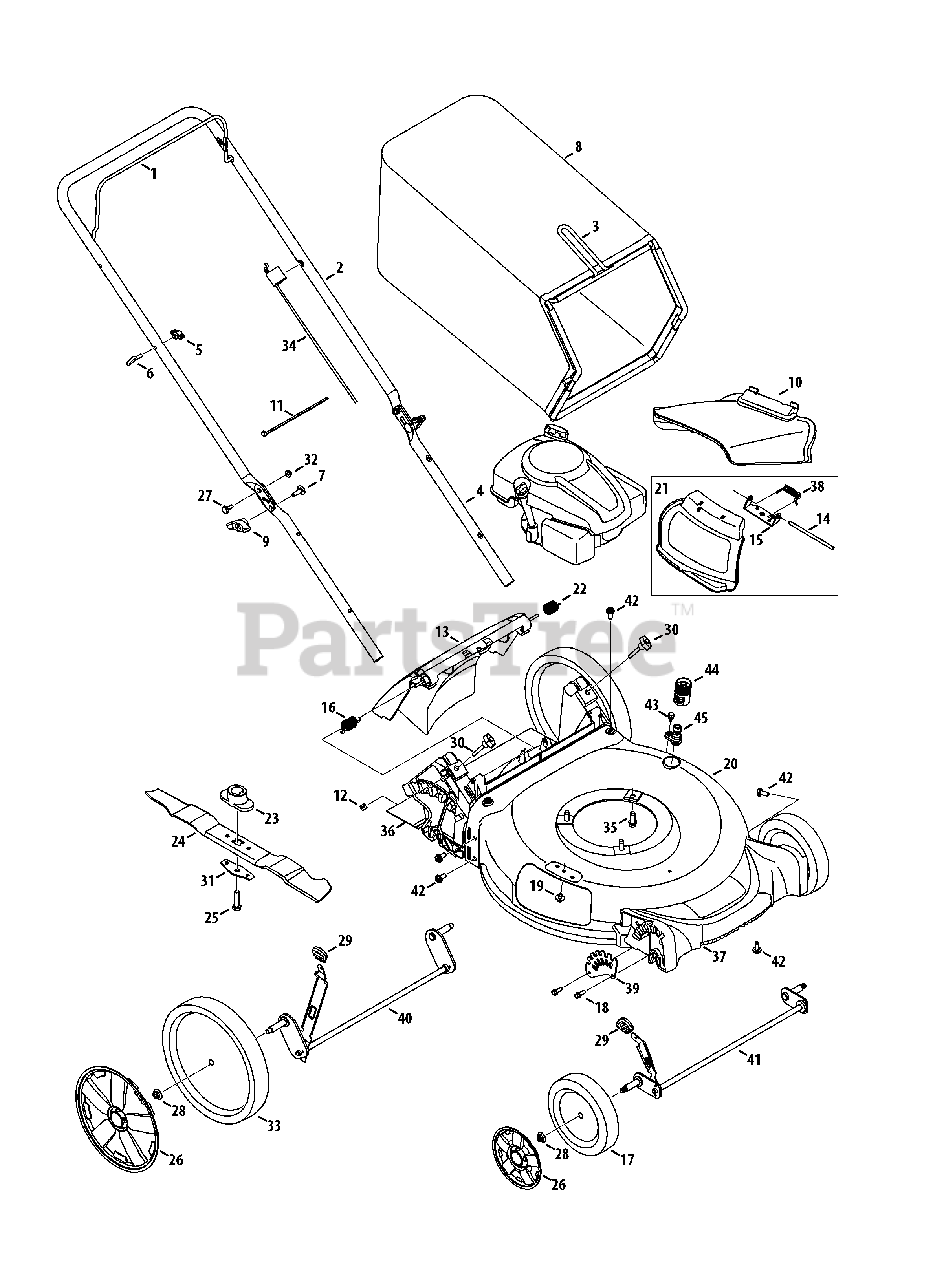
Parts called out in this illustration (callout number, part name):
1	Blade Control
2	Upper Handle
4	Lower Handle
5	Wing Nut
6	Rope Guide
7	Carriage Screw ,5/16-18
8	Grass Bag
9	Wing Knob
10	Side Chute
11	Cable Tie
12	Nut, Sq., 1/4-20
13	Rear Discharge Door Assembly
14	Hinge Pin
15	Chute Deflector Bracket
16	Torsion Spring - RH
17	Wheel, 7 x 2
18	Screw, 1/4-15 x .750
19	Screw, 1/4-20 x .500
20	Deck - 21"
21	Hinged Mulch Plug Assembly
22	Torsion Spring - LH
23	Blade Adapter
24	Mulching Blade
25	Screw , 3/8-24 x 1.50
26	Hub Cap - Front
26	Hub Cap - Rear
27	Sldr. Screw, .375 x .126 x 1/4-20
28	Flange Lock Nut, 3/8-16
29	Adjustment Lever Knob
30	Wing Nut
31	Blade Bell Support
32	Nut, Flange Lock, 1/4-20
33	Wheel, 11 x 2
34	Control Cable
35	TT Screw, 3/8-16 x 1.0
36	Trail shield
37	Front Cover
38	Torsion Spring
39	Front Height Adjuster Plate
40	Rear Axle Assembly
41	Front Axle Assembly
42	Screw, 5/16-14 x .750
43	Shldr. Screw, 1/4-20 x .50
44	Water Nozzle Adapter
45	Deck Wash Nozzle
